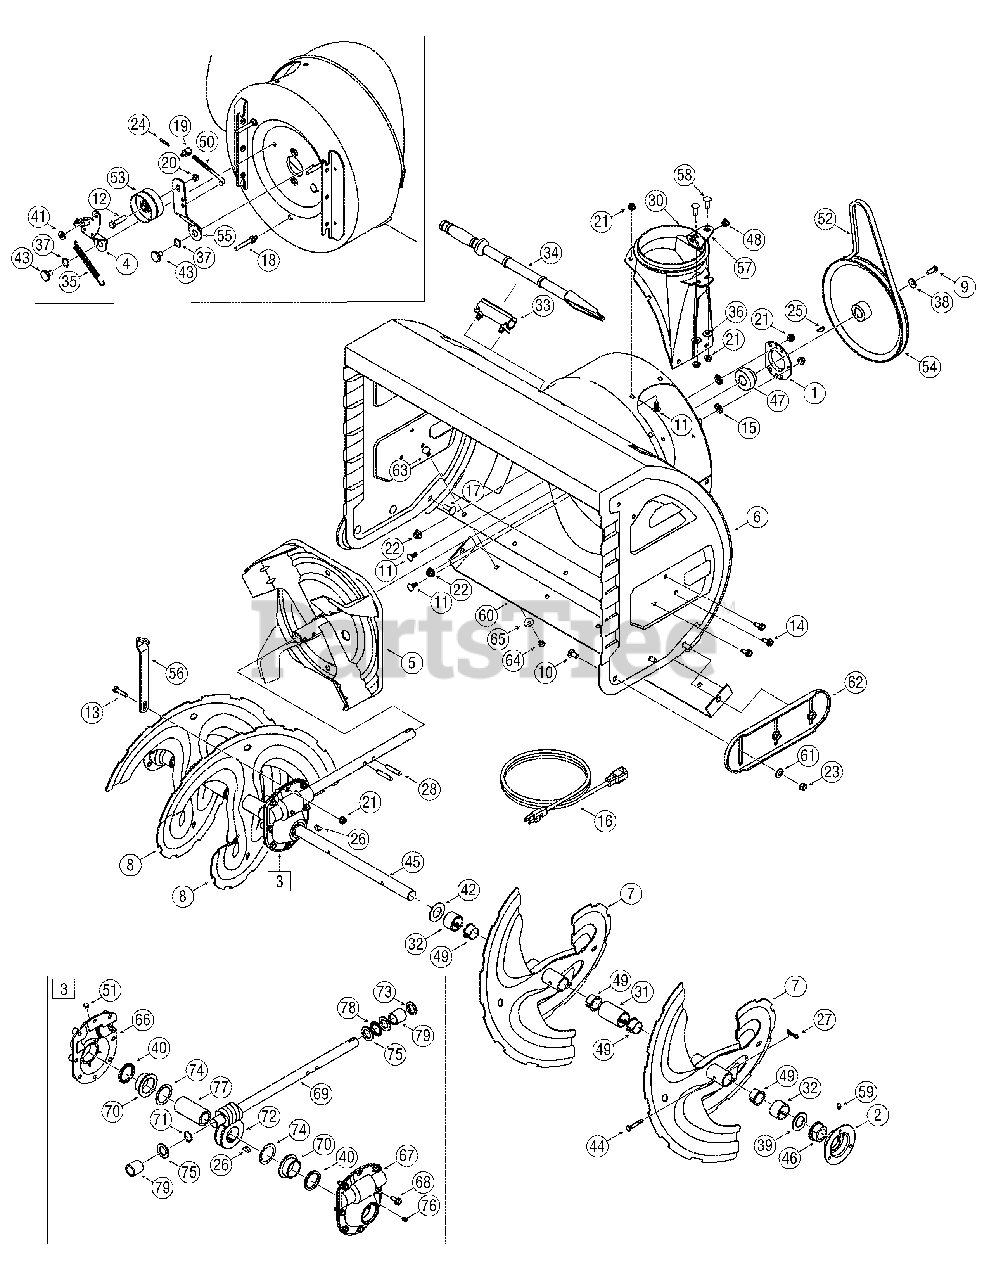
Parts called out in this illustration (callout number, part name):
1	Housing, Bearing
3	Gear Box Assembly, Auger
4	Bracket Assy, Auger Brake
9	Screw, Hex Cap Lock
10	Screw, Carriage, Stnls Stl
11	Screw, Carriage, 5/16-18 x .75
12	Scr, Hex Cap, 3/8-24 x 1.5
13	Scr,Hex Cap, 5/16-18 x 1.25
14	Screw, 5/16-18 x .750
16	Extension Cord, 110V
17	Screw, Carriage, 3/8-16 x 1.0
18	Screw, 5/16-18 x .4300
19	Ferrule
20	Nut, Hex Lock, 3/8-24
21	Nut, Flnge Lk, 5/16-18
22	Nut, Flg Lk, 3/8-16
23	Nut, Hex, Stnls Stl, 3/8-16
24	Pin, Internal Cotter
25	Key, Hi Pro, 3/16 x 3/4
26	Key, Woodruff,1/4 x 3/4
27	Pin, Bowtie Cotter
28	Pin, Spirol, 5/16 x 1.75
30	Adapter, Chute, 6"
31	Spacer, 1.0 x 1.5 x 2
32	Spacer, 1.0 x 1.5 x 1
33	Clip, Mounting
34	Tool, Cleanout
35	Spring, Extension
36	Washer, .349 x .879 x .063
37	Washer, .625 x .885 x .015
38	Washer, .34 x .872 x .06
39	Spacer, 1.004 x 1.375 x .25
40	Oil Seal
41	Washer, .344 x .75 x .12
42	Washer, 1.01 x 1.86 x .06
43	Screw, Shoulder, .625 x .17
44	Pin, Shear, .25 x 1.75
45	Axle, Spiral, 30"
46	Bearing, Flange w/Flats
47	Bearing, Self Aligning
48	Bushing, Nylon
49	Bushing, Flange, 1.051 x 1.16
50	Rod, Auger Idler
52	V Belt,1/2 x 44
52	V Belt 1/2 x 42
53	Pulley, Flat Idler, 2.75 OD
54	Pulley, Auger Drive, 10.0
55	Bracket, Auger Idler
58	Screw, Carriage, 5/16-18 x 1.00
59	Ftg, 3/16
60	Plate, Shave, 30"
60	Plate, Shave, 33"
61	Washer, Bell, .37x.87x.06
63	Screw, Carriage, 5/16-18 x .75
64	Nut, Hex, Stnls Stl,
65	Washer, Bell, .34x.87x.06
66	Hsg Assy Auger RH (Inc. 40 & 70)
67	Hsg Assy Auger LH (Inc. 40 & 70)
68	Screw, LD, 5/16-18 x .750
69	Shf, Drive, Auger
70	Flange Bearing
71	Ext, Ret, Ring
72	Gear, Worm, LH
73	Seal, Oil
74	Washer, Flat, 1.52 ID x 2.0 OD
75	Washer, Flat, .88 ID x .38 OD
76	3/16 Drive Lube Fitting
77	Shf, Gear, Worm
78	Brg, Thrust
79	Sleeve
